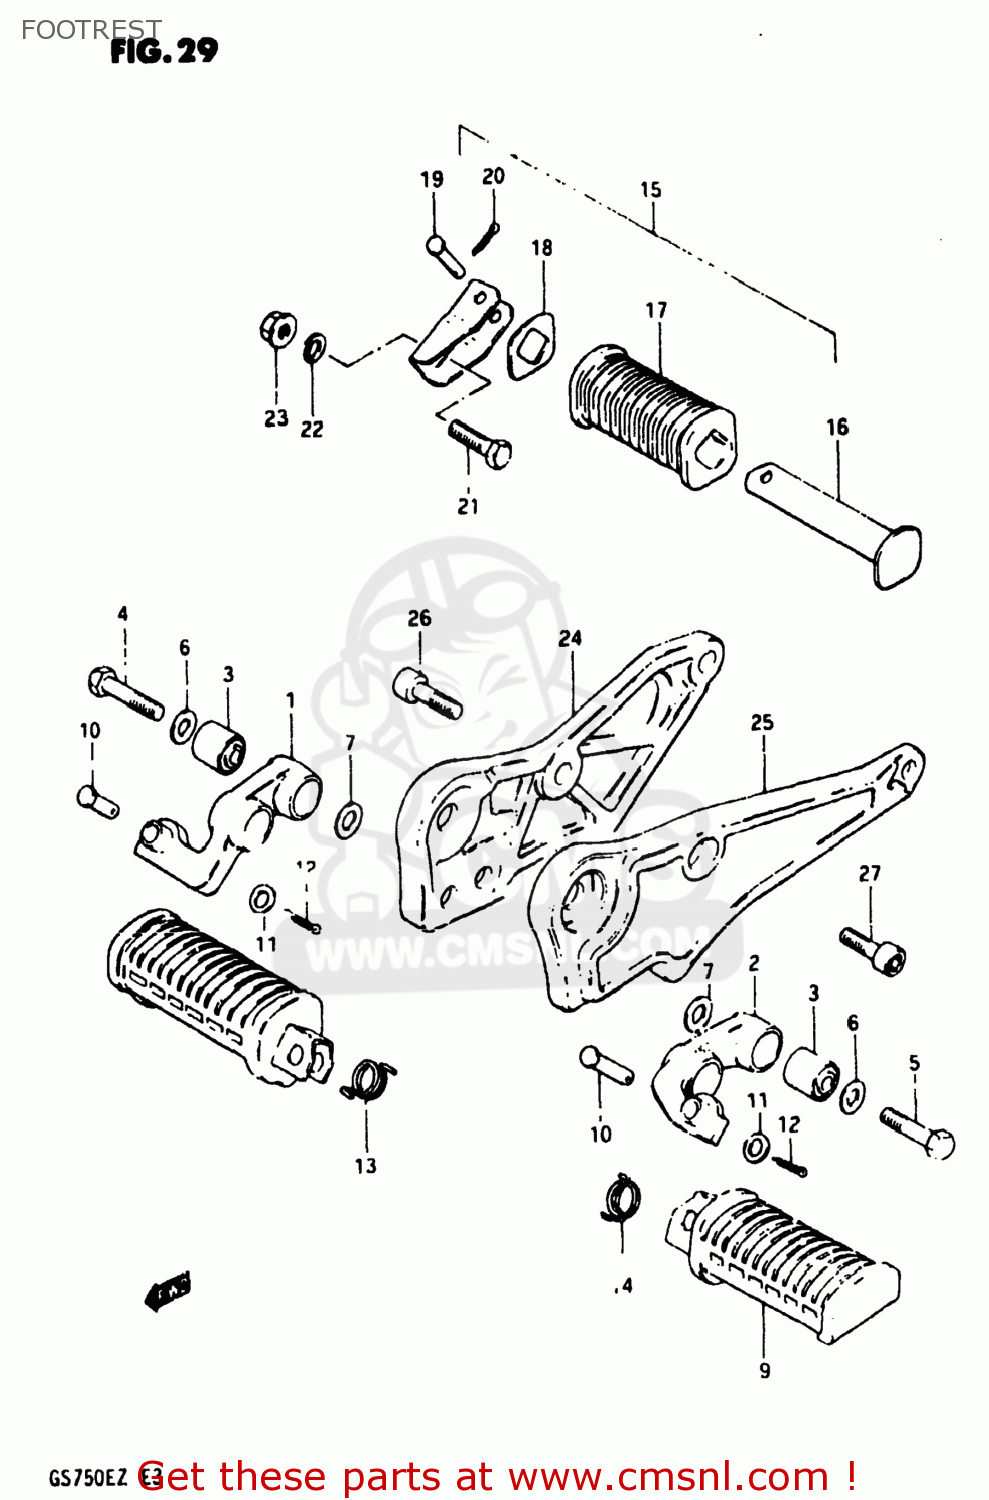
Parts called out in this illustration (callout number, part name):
1	BAR,FRONT FOOTREST,RIGHT
2	BAR,FRONT FOOTREST,LEFT
3	BUSH
4	BOLT(10X50)
5	BOLT
6	WASHER
7	WASHER
8	RUBBER,FOOTREST
9	FOOTREST
10	PIN
11	WASHER
12	PIN
13	SPRING
14	SPRING
15	FOOTREST ASSEMBLY,REAR
16	BAR,REAR FOOTREST
17	RUBBER,REAR FOOTREST
18	WASHER,REAR FOOTREST RUBBER
19	PIN
20	PIN
21	BOLT,M10X1.25X
22	LOCK WASHER
23	NUT
24	BRACKET,MUFFLER,RIGHT
25	BRACKET
26	BOLT
27	BOLT
